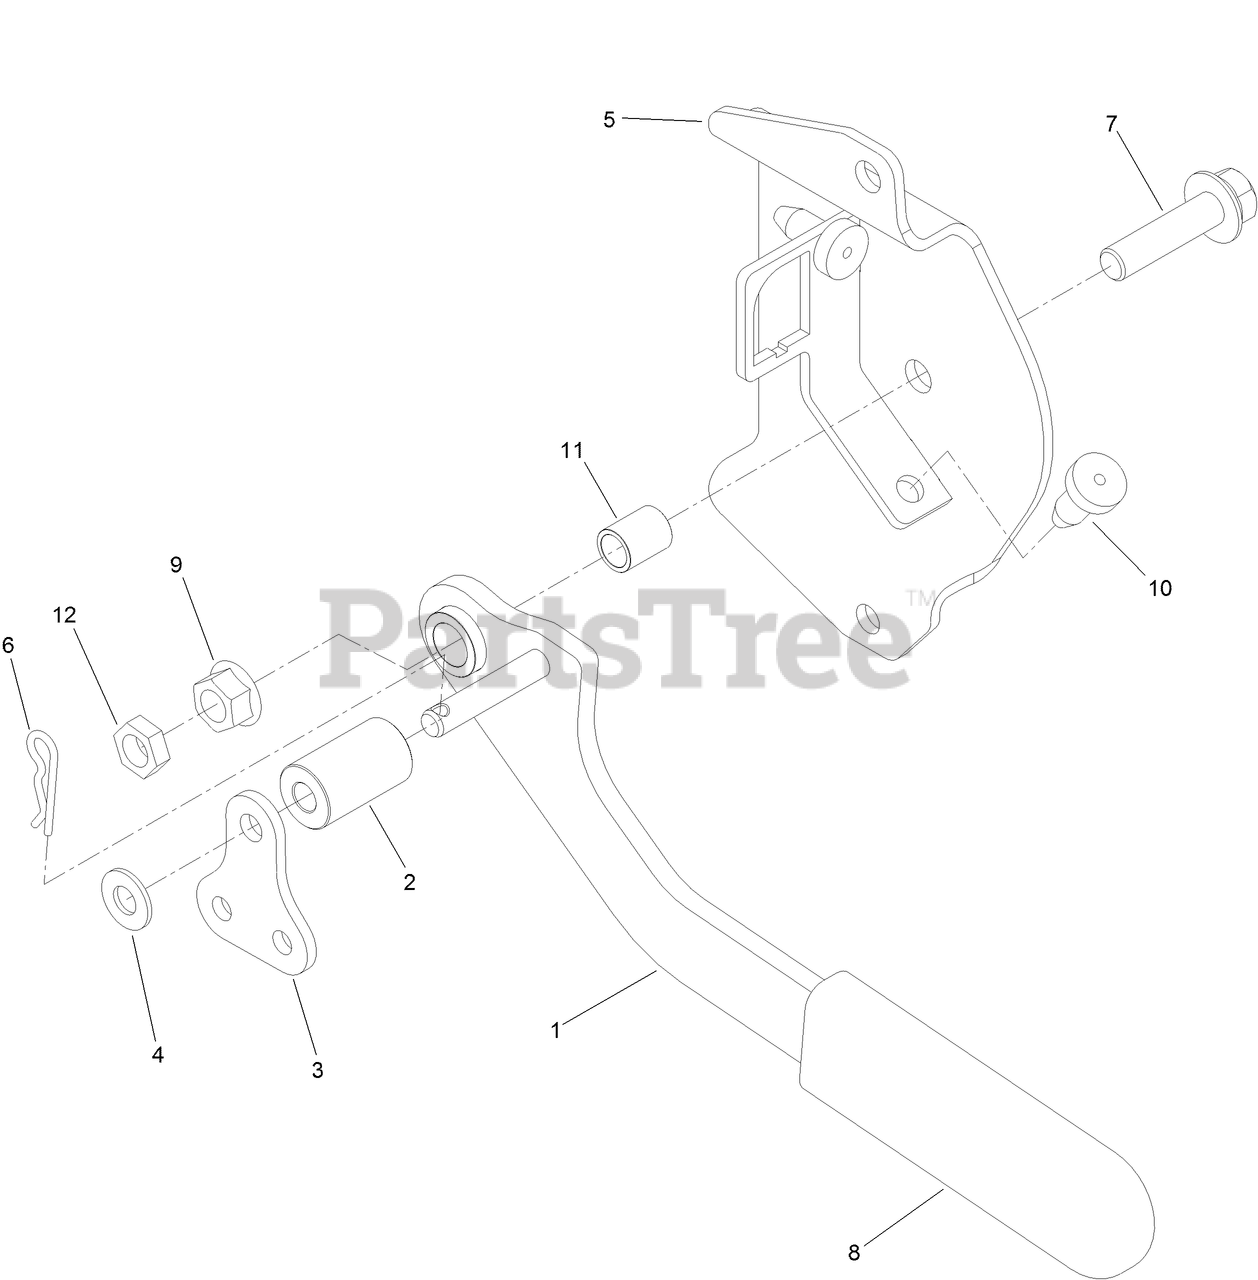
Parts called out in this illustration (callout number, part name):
1	HANDLE-BRAKE
2	SPACER
3	YOKE-CABLE
4	SPACER-NYLON
5	BRACKET ASM-BRAKE
6	PIN-COTTER
7	SCREW-HHF
8	GRIP-LEVER
9	NUT-HF
10	BUMPER-RUBBER
11	BEARING-SLEEVE
12	NUT-JAM
